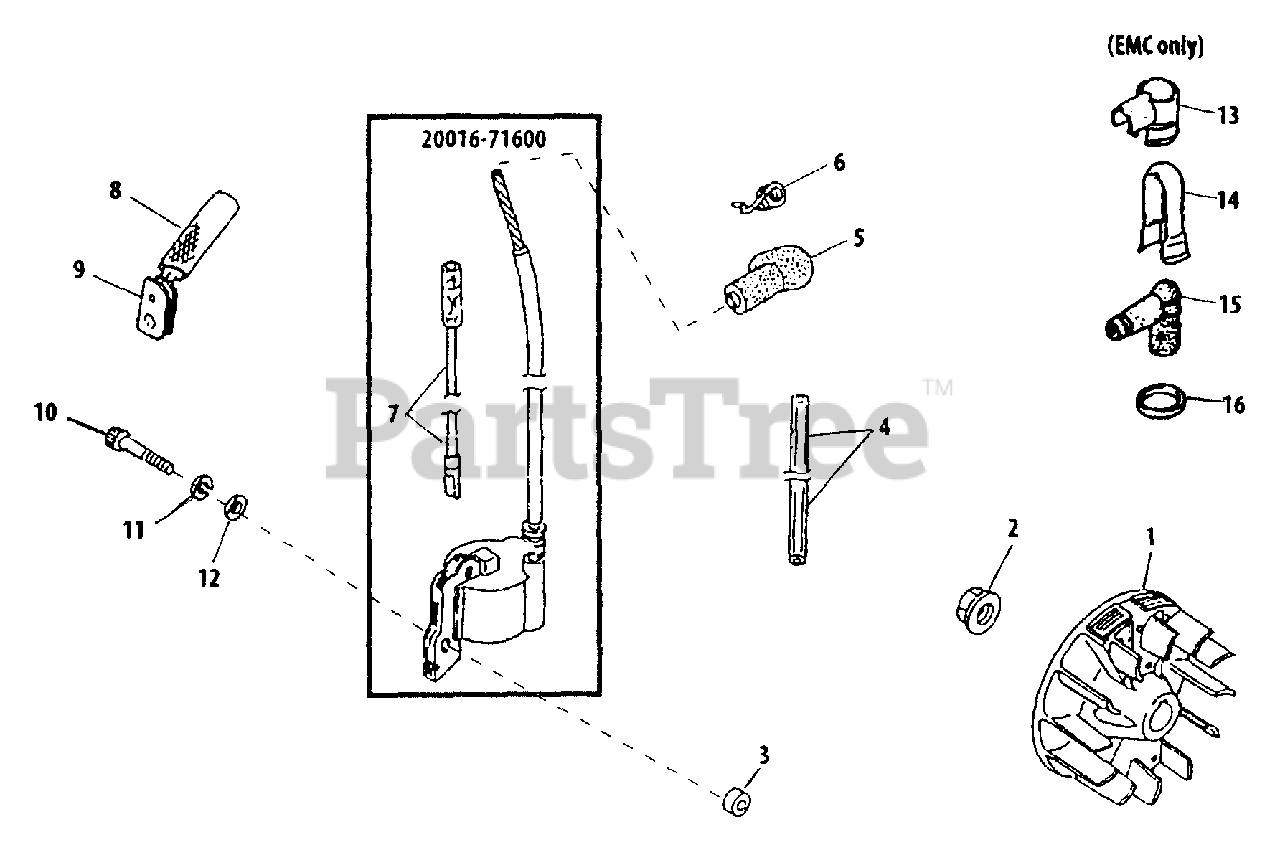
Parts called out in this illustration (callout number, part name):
1	FLYWHEEL
2	NUT - 8
3	INSULATOR
4	TUBE
5	CAP, SPARK PLUG
6	TERMINAL, SPARK PLUG CAP
7	LEAD - IGNITION
8	TUBE
9	GROMMET
10	SCREW - 4X26
11	LOCKWASHER - 4
12	WASHER - 4
13	CAP, SPARK PLUG
14	SHIELD
15	CAP, SPARK PLUG
16	SEAL, DUST
20016-71600	IGNITION COIL ASSY
